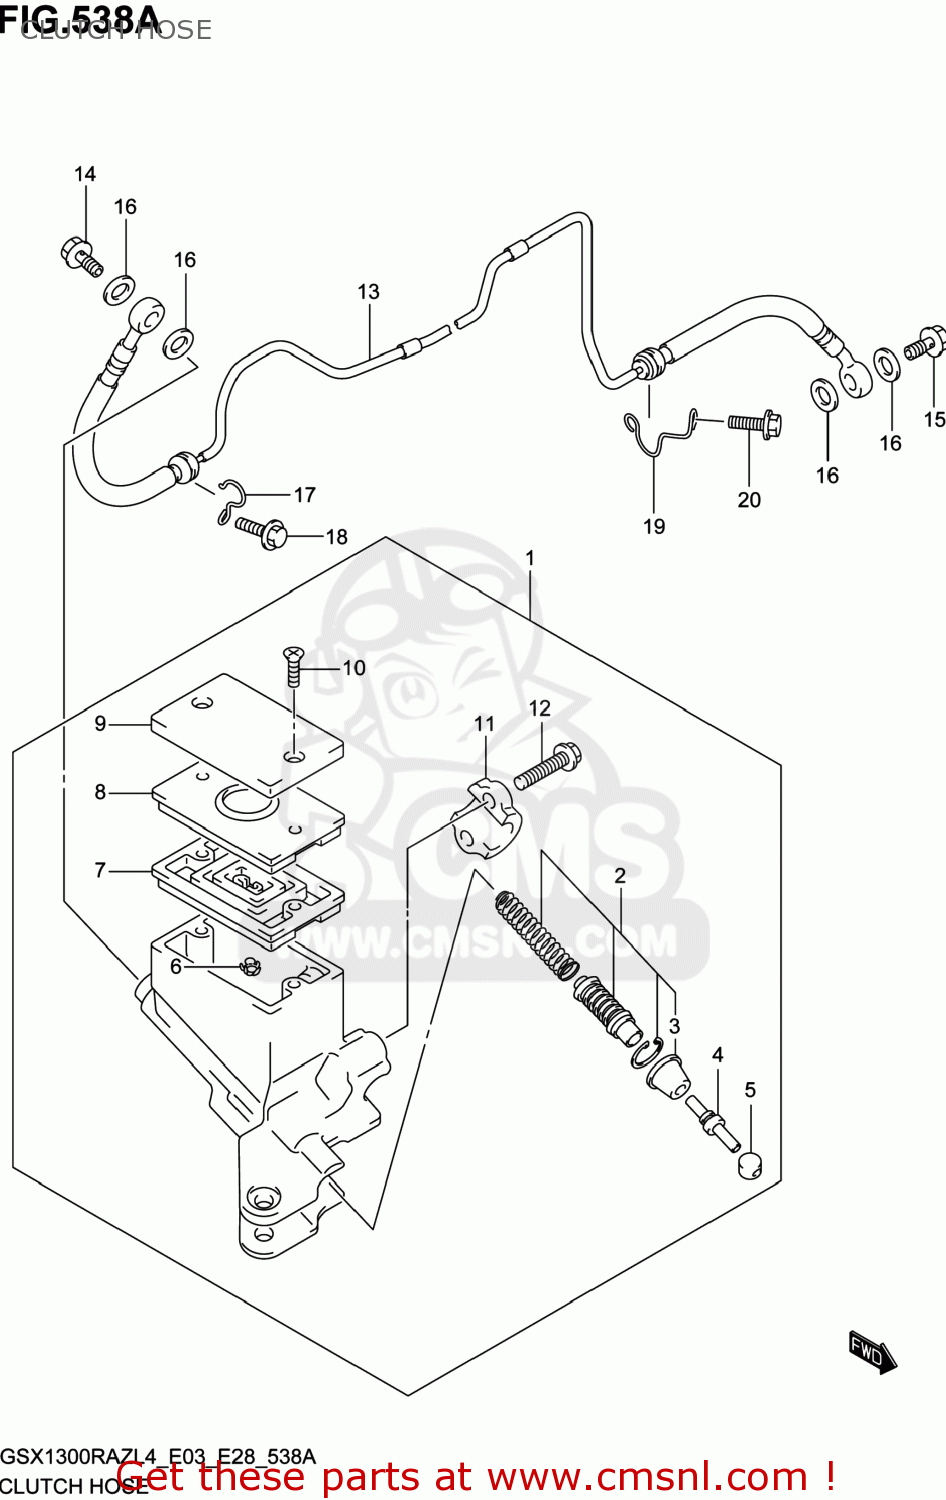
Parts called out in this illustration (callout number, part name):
1	CYLINDER ASSY,CLUTCH MASTER
2	PISTON & CUP SET
3	BOOT
4	ROD,PUSH
5	BUSH
6	PROTECTOR
7	8
8	PLATE,DIAPHRAGM
9	CAP
10	SCREW
11	HOLDER
12	BOLT
13	HOSE,CLUTCH
14	BOLT UNION
15	BOLT UNION
16	WASHER(10X15X1.5)
17	CLAMP,CLUTCH HOSE NO.1
18	BOLT
19	CLAMP,CLUTCH HOSE NO.2
20	BOLT
